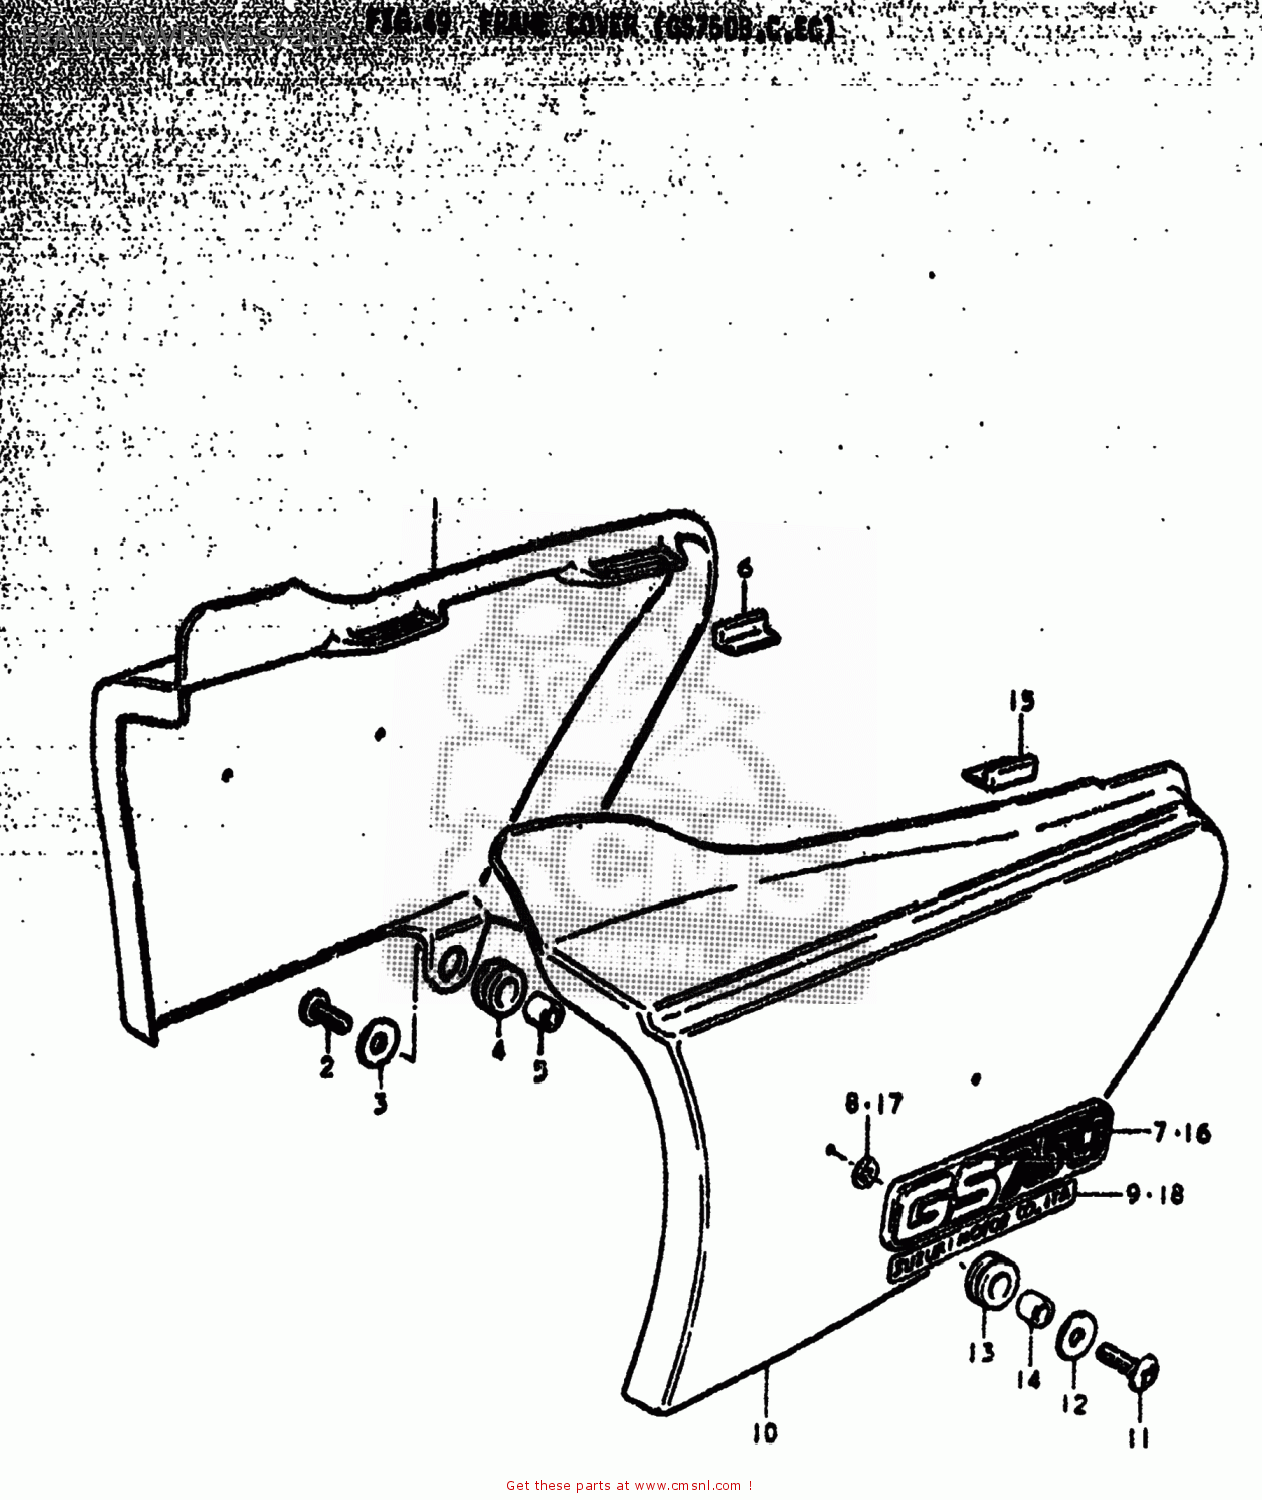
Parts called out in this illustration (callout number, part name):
1	COVER,FRAME,RIGHT
2	SCREW (6X20)
3	WASHER (6.5X18X1.6)
4	CUSHION
5	SPACER (6.8X10X10)
6	CUSHION,FRAME COVER
7	EMBLEM,FRAME COVER
8	NUT
9	LABEL,COMPANY NAME
10	COVER,FRAME,LEFT
11	SCREW (6X20)
12	WASHER (6.5X18X1.6)
13	CUSHION
14	SPACER (6.8X10X10)
15	CUSHION,FRAME COVER
16	EMBLEM,FRAME COVER
17	NUT
18	LABEL,COMPANY NAME
